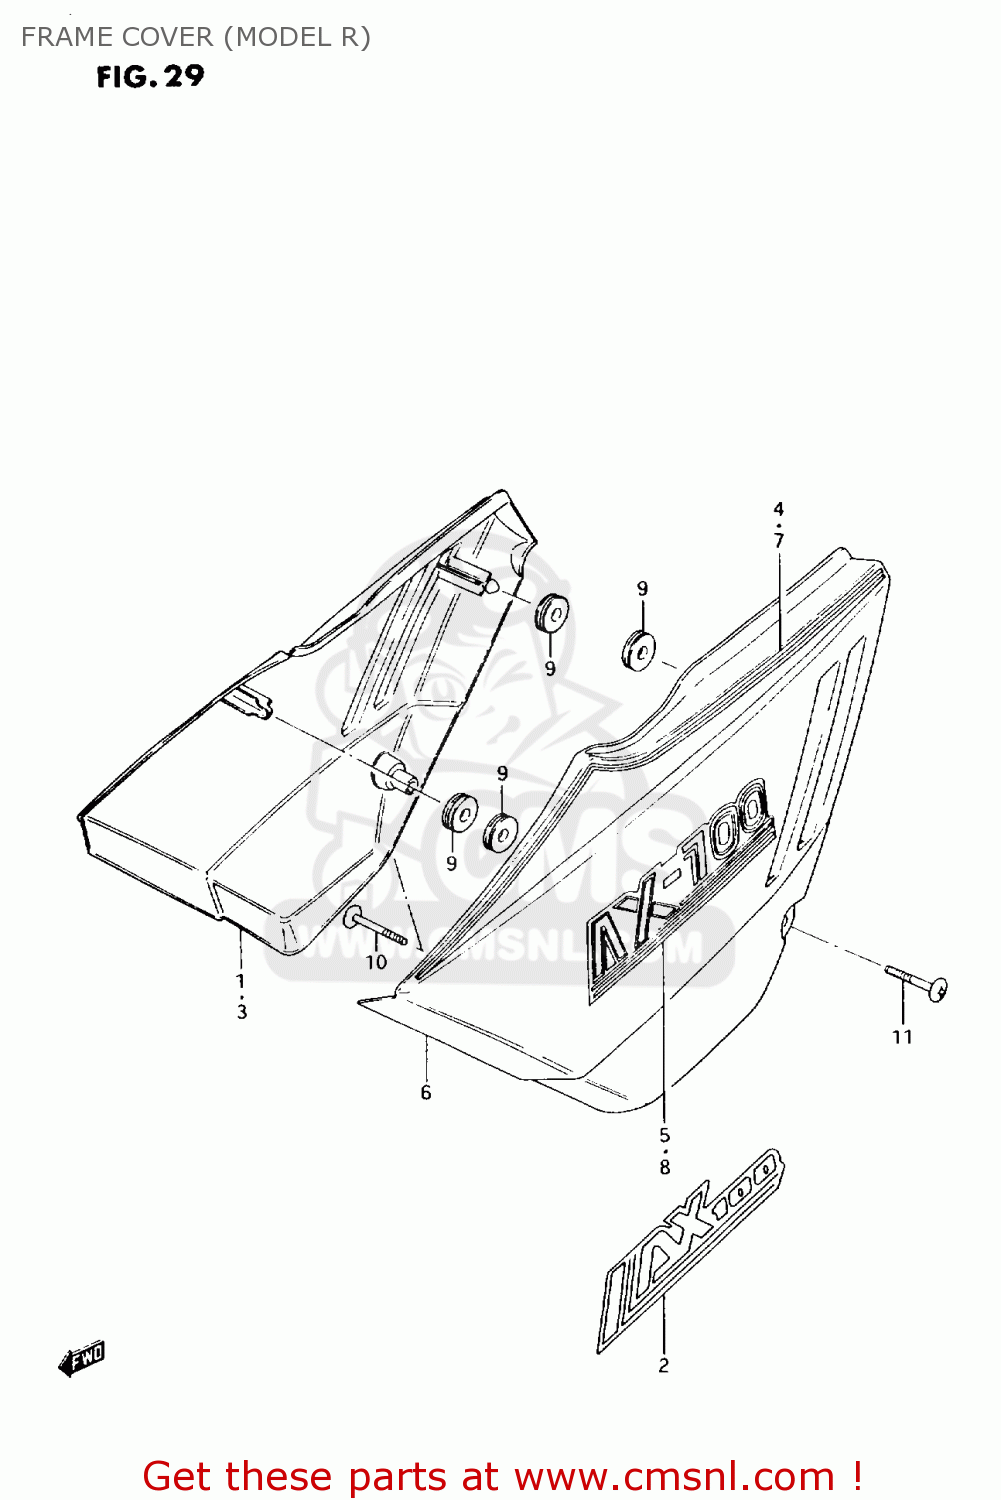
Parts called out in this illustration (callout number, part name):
1	COVER,FRAME,R
2	EMBLEM
3	COVER,FRAME,R
4	TAPE SET, FRAME COVER RH
5	EMBLEM
6	COVER,FRAME,L
7	TAPE SET, FRAME COVER LH
8	EMBLEM
9	CUSHION
10	SCREW
11	SCREW(6X45)
